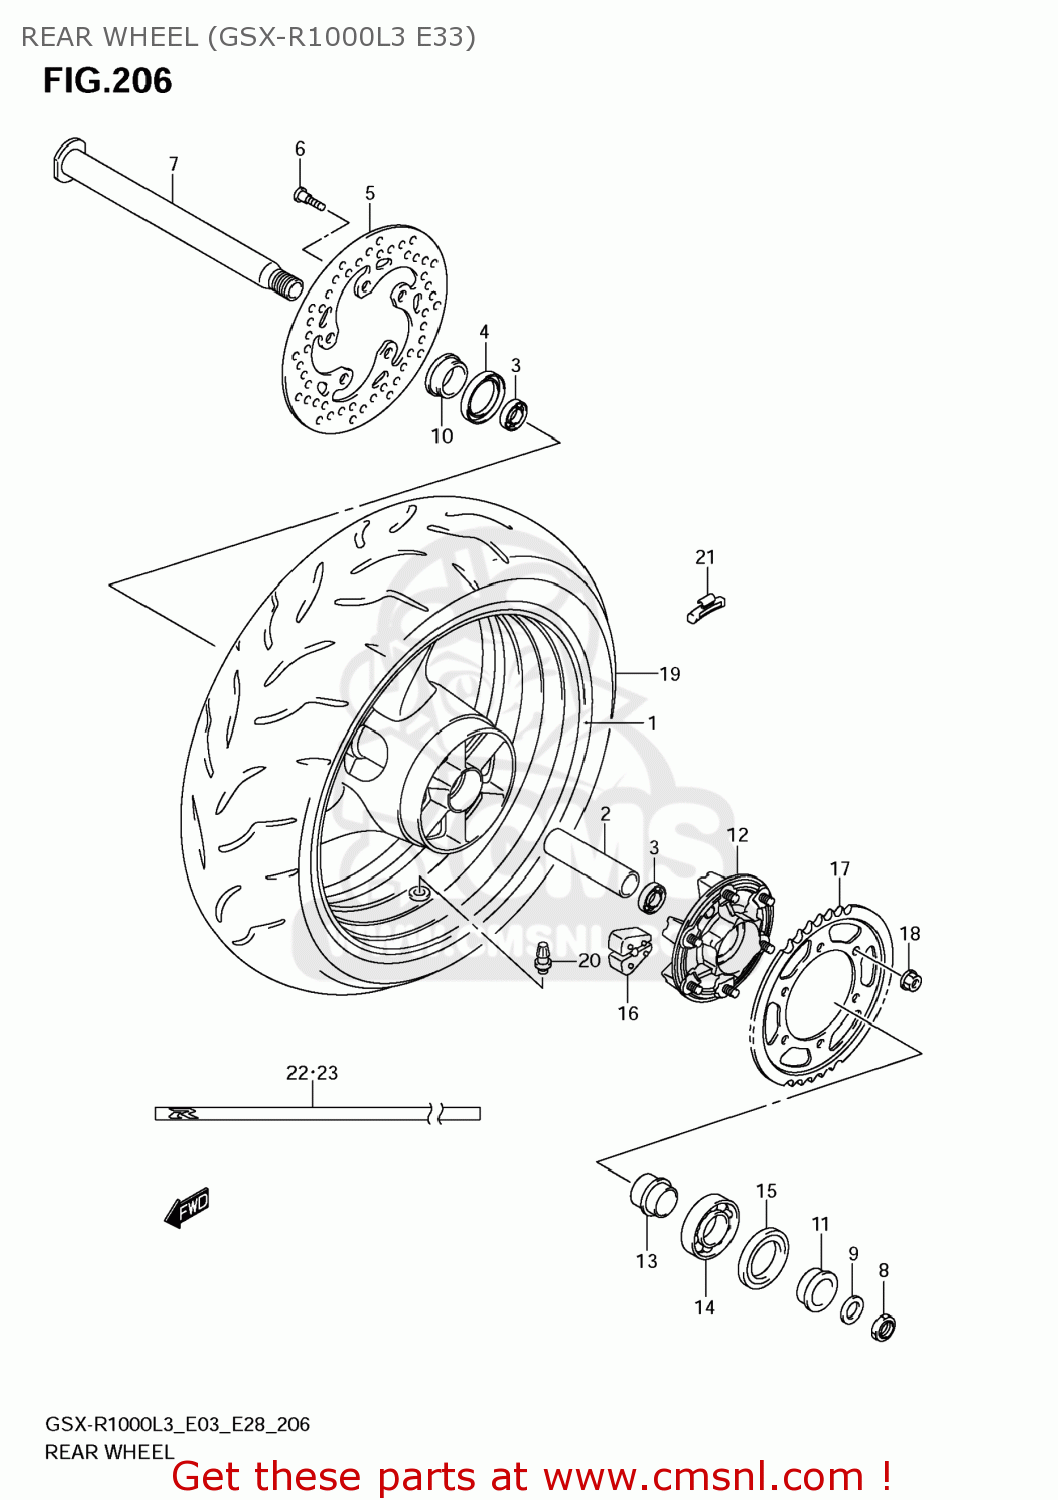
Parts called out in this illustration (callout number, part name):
1	WHEEL,RR(17M/CXMT6.00)
2	SPACER,RR HUB BEARING
3	BEARING(28X52X12)
4	SEAL,OIL(37X52X8)
5	DISC,RR BRAKE
6	BOLT(8X21)
7	AXLE,RR
8	NUT
9	WASHER(25.2X42X3.2)
10	SPACER,RR AXLE,R
11	SPACER,RR AXLE,L
12	DRUM,RR SPROCKET
13	RETAINER,RR SPROCKET DRUM
14	BEARING(32X65X17)
15	SEAL,OIL(39X65X7)
16	ABSORBER,RR HUB SHOCK
17	SPROCKET,RR(42T-530)
18	NUT
19	TIRE,RR
20	VALVE ASSY,WHEEL RIM(TR412)
21	BALANCER,WHEEL(10G)
22	TAPE,WHEEL FR,R
23	TAPE,WHEEL FR,L
